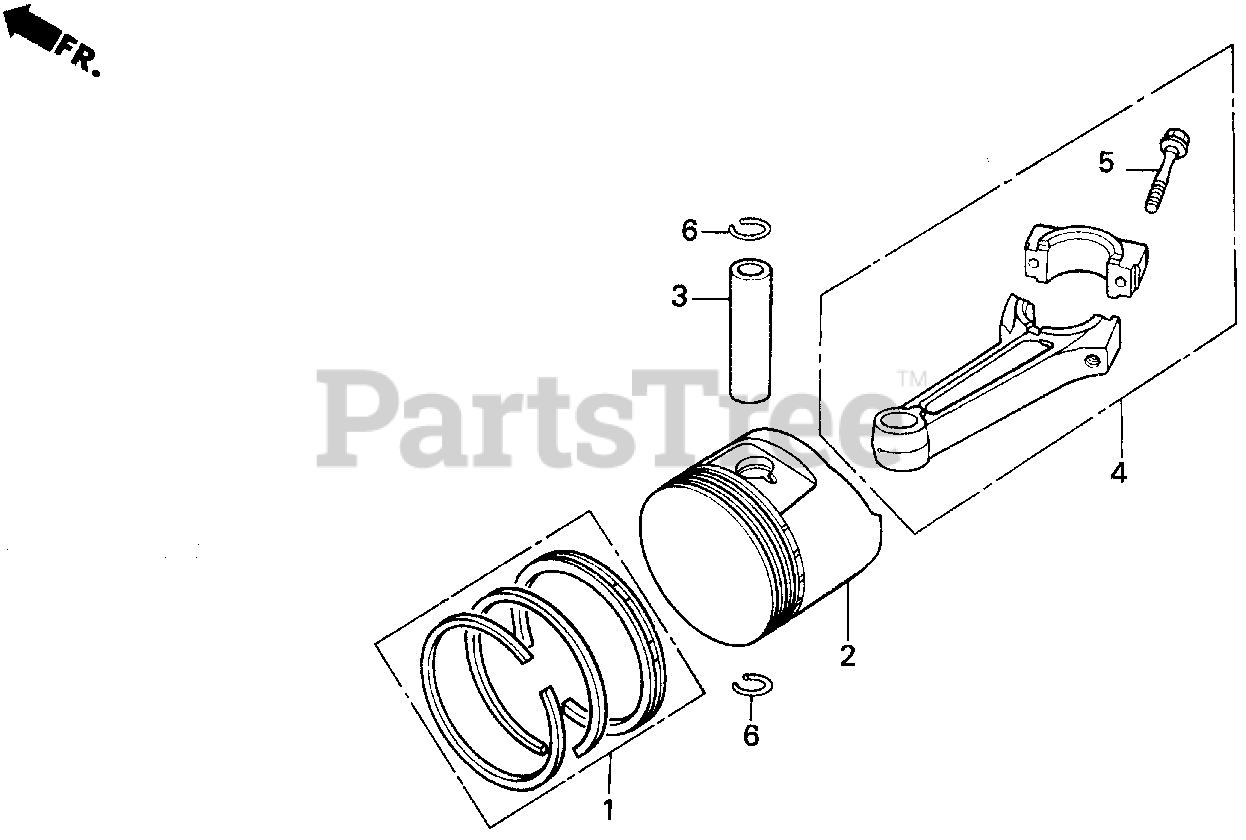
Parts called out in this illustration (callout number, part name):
1	RING SET, PISTON (STD)
1	RING SET, PISTON (OS 0.25)
1	RING SET, PISTON (OS 0.50)
1	RING SET, PISTON (0.75)
2	PISTON (STD)
2	PISTON (OS 0.25)
2	PISTON (OS 0.50)
2	PISTON (0.75)
3	PIN, PISTON
4	ROD ASSY., CONNECTING
4	ROD ASSY., CONNECTING (Honda Code 2953107). (US 0.25)
5	BOLT, CONNECTING ROD
6	CLIP, PISTON PIN (20MM)
